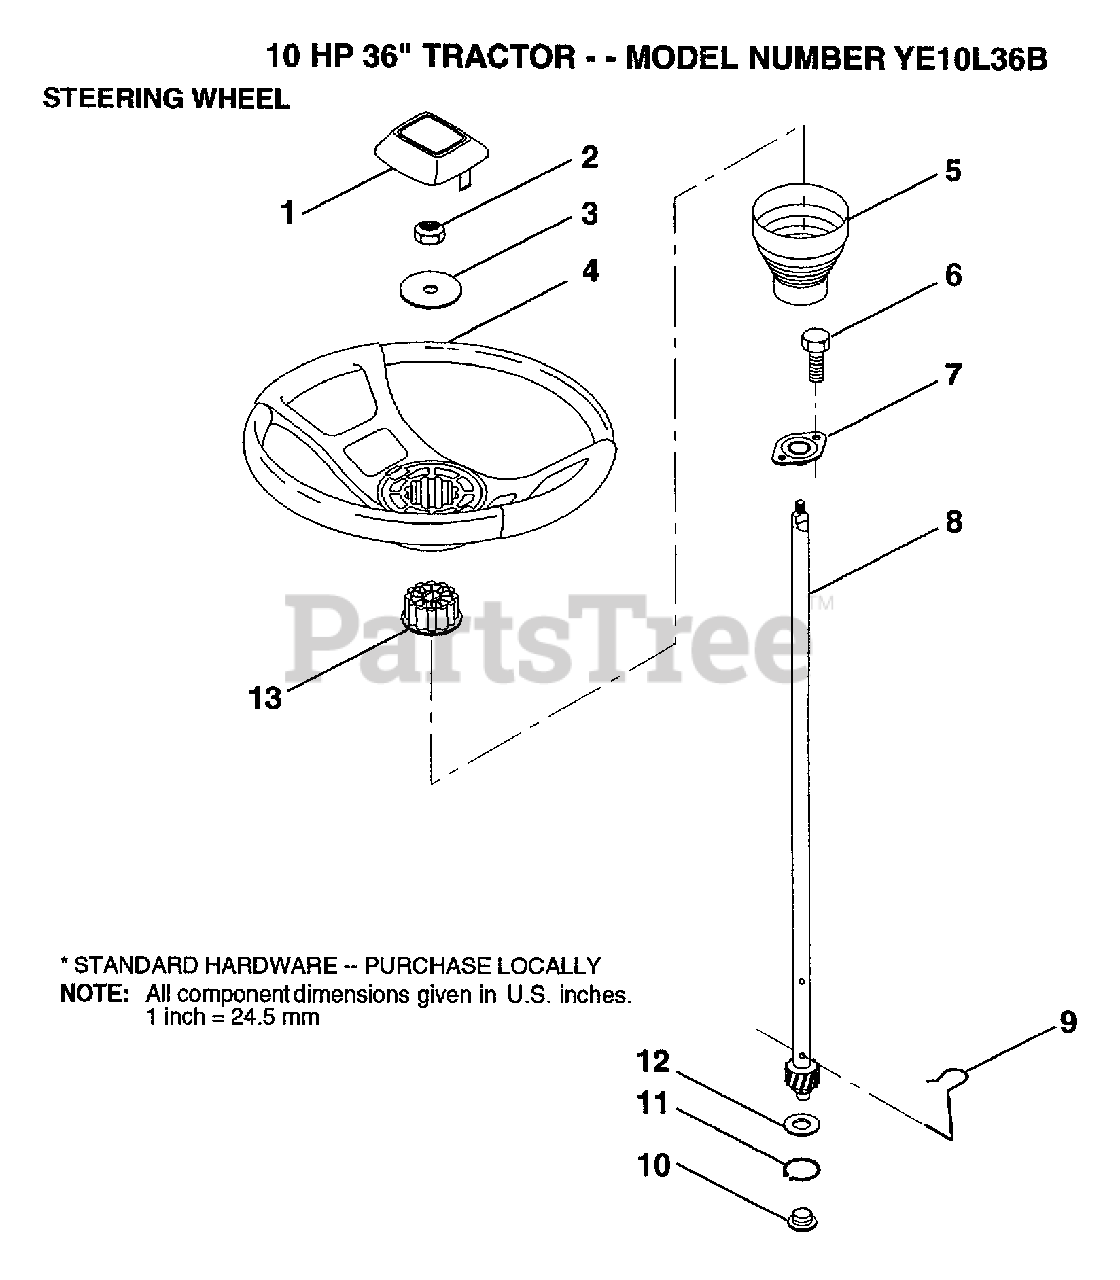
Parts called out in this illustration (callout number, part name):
1	INSERT STEERING
2	GRIPCO NUT
3	WASHER T
5	SLEEVE STEERING
9	STEERING CLIP
10	BUSHING STEER LWR
11	RING
12	WASHER LT
13	ADAPTER-WHEEL LT
